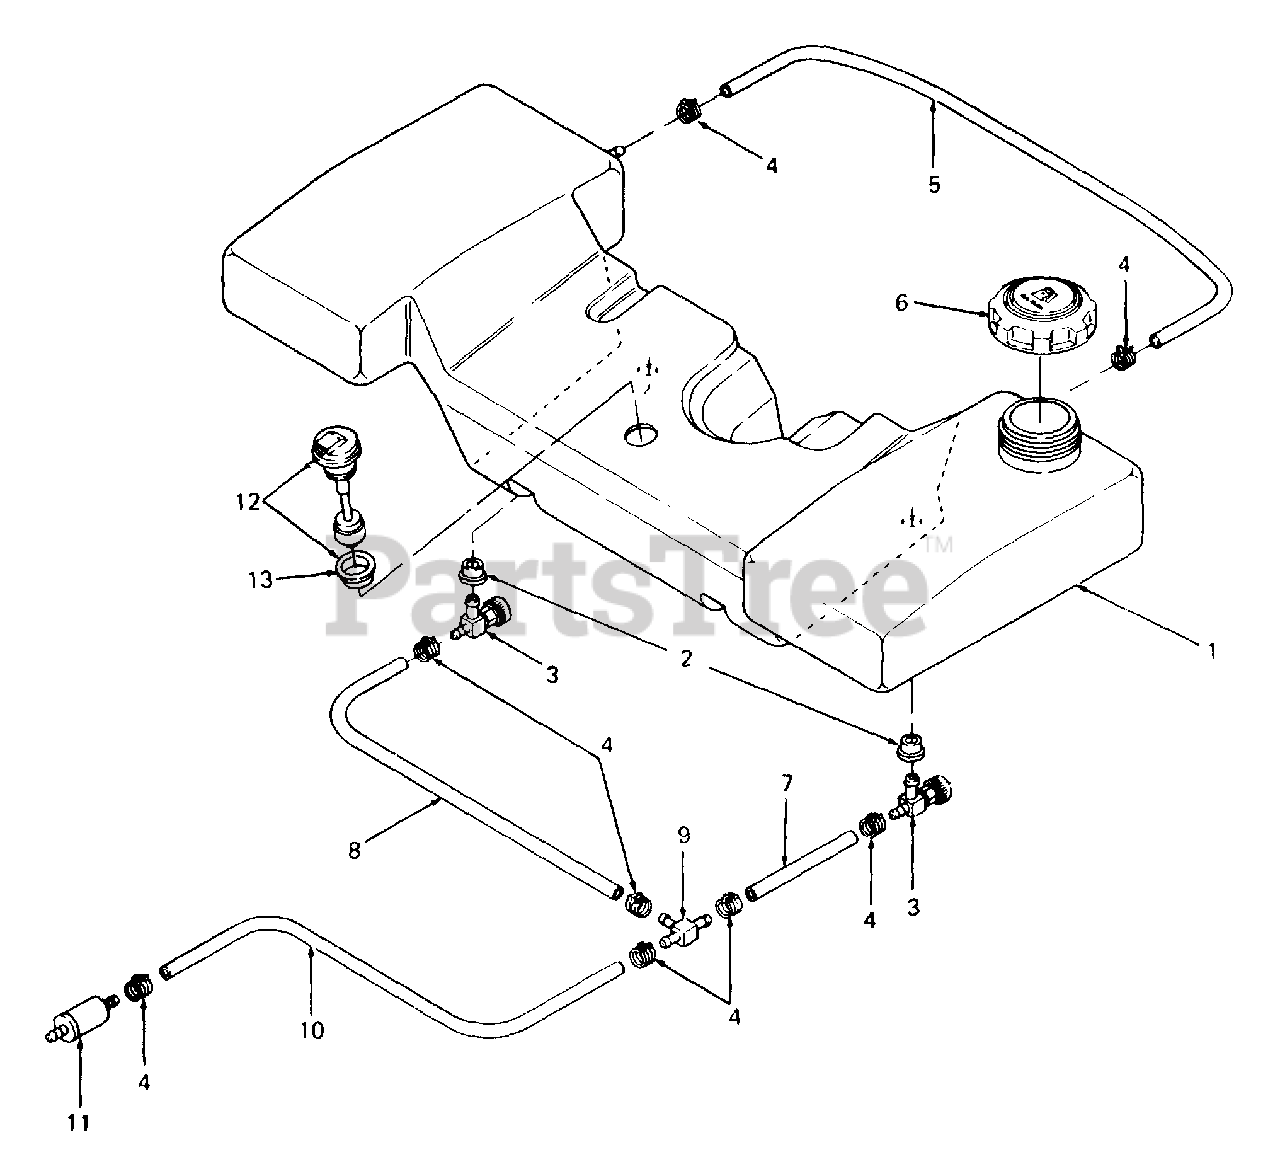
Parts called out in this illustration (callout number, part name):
1	Tank, Fuel
2	Bushing
3	Valve, Fuel Shutoff
4	Clamp, Hose
5	Line, Fuel - 24" Lg
6	Cap, Fuel
7	Line, Fuel - 5" Lg
8	Line, Fuel - 19" Lg
9	T-Fitting
10	Line, Fuel - 41" Lg
11	Filter, Fuel
12	Sensor, Low Fuel
13	Bushing, Rubber
